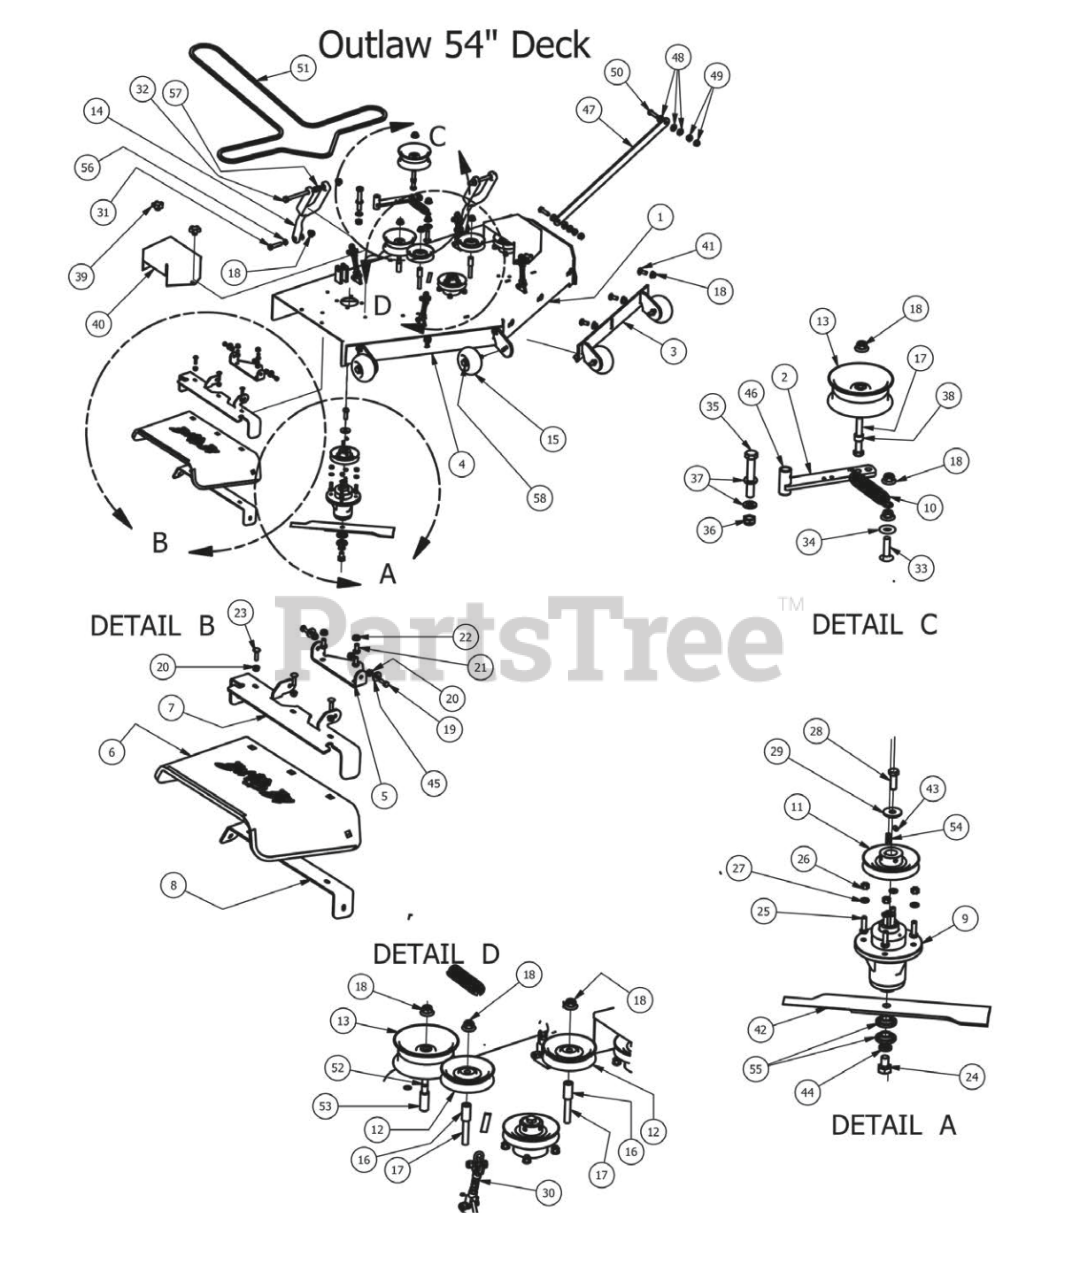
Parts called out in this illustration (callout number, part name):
1	54" Outlaw (Deck Only)
2	Deck Idler Bracket
3	54 Outlaw Adjustable Deck Front (Right)
4	54 Outlaw Adjustable Deck Front (left)
5	Discharge Chute Hanger (deck mounted)
6	Rubber Discharge Chute
7	Dischurge Chute Upper Hanger
8	Lower Hanger
9	Double Bearing Spindle
10	2009 Deck/Pump Idler Spring
11	5" Deck Pulley
12	4 3/4" Idler Pulley
13	5 3/4 Flat Idler-32FI-92-008
14	Deck Hanger
15	Deck Wheel
16	Pulley Spacer
17	1/2 x 3 1/2 Flange Bolt Grade 8
18	1/2-13 Nylon Flange Nut-Orange
19	5/16" x 1" Bolt
20	5/16" Flange Nut
21	3/8" x 3/4" Hex Bolt
22	3/8" Flange Nut
23	5/16" x 1 1/4" Carriage Bolt
24	5/8" x 1 1/2" Grade 8 Bolt
25	3/8" x 1 1/4" Hex Bolt
26	3/8-16 Hex Nuts Zinc
27	3/8" Lock Washer
28	1/2"-20 x 1 1/2 - Grade 5 Fine Thread Bolt
29	1/2 Belleville Washer
30	2-Link Adjustable Deck Hange
31	1/2-13X 2-1/4 GR Hex Bolts
32	1/2" x 5 1/2" Bolt
33	1/2 x 2" Carriage Bolt
34	1/2" Flat Washer
35	5/8" x 4" Hex Bolt
36	5/8" Nylock (1/2 Jam)
37	.635 ID Plastic Washer
38	Spacer 3/4 OD X 1/2 ID x .75
39	5/16" Knob
40	Pulley Cover
41	1/2" x 1 1/4 Carriage Bolt
42	54" Deck Fusion Blade For Outlaw
43	3/8" Set Screw
44	5/8" Lock Washer
45	.360 ID Plastic Washer
46	Deck Idler Assembly Componets13,18,17,38,2
47	Panhard Linkage Bar
48	.505 Nylon Spacer
49	1/2" Flange Nut
50	1/2-13x2 GR 5 Hex Bolt
51	B165 Belt-60 54" deck Outlaw
52	1/2" x 4" Bolt (Grade 8)
53	1 3/4" Pulley Spacer
54	1/4" x 1" Key
